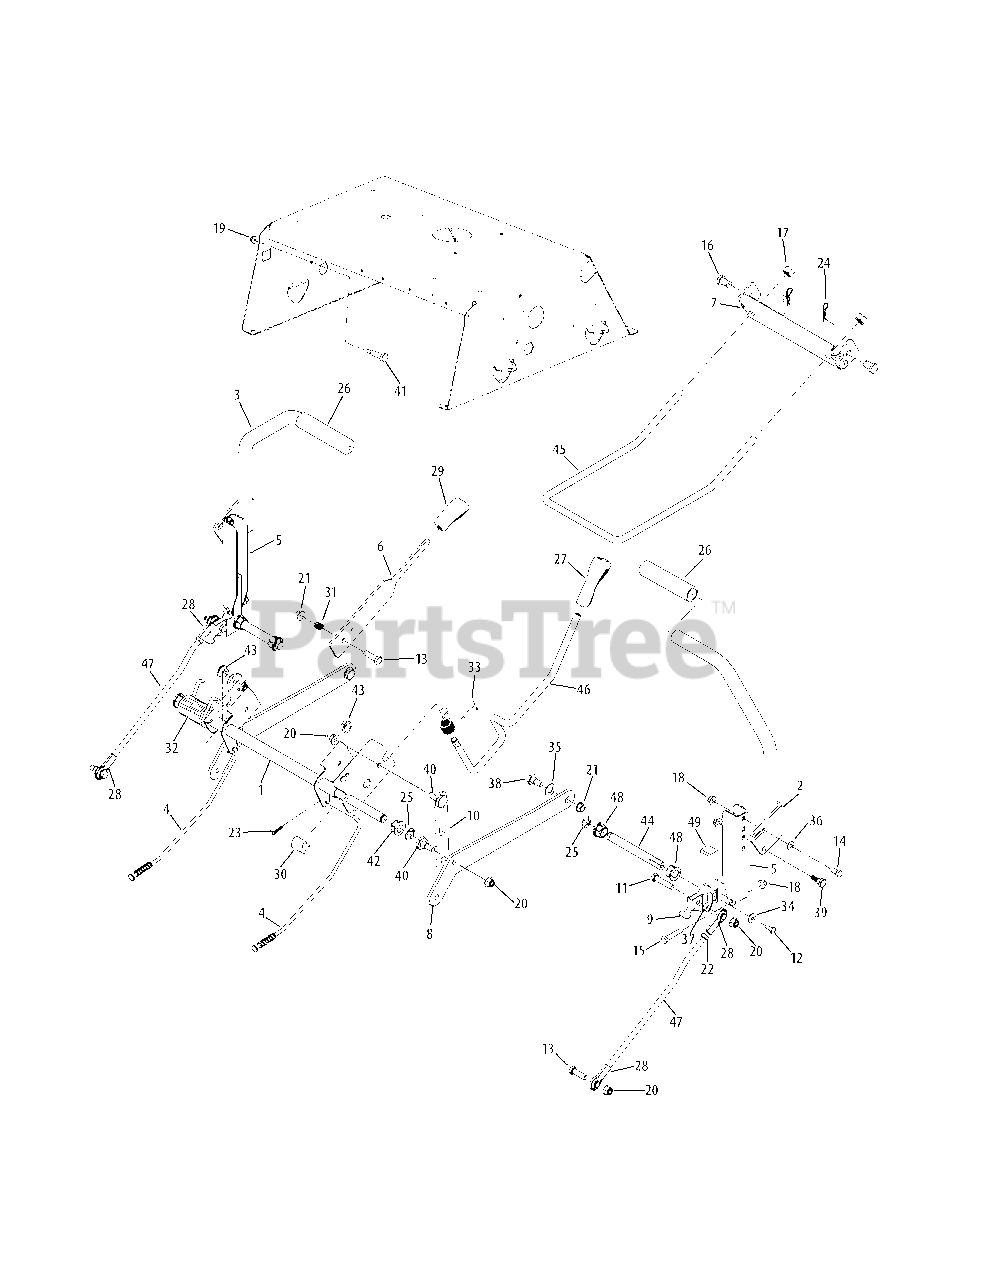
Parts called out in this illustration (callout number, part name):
1	Deck Lift Shift Assembly
2	RH Lapbar Lever Assembly - Black
2	RH Lapbar Lever Assembly - Gray
3	LH Labpar Lever Assembly - Black
3	LH Labpar Lever Assembly - Gray
4	Brake Rod Assembly
5	Lapbar Pivot Bracket
6	Brake/Shabs Assembly
7	Front Deck Hanger Bracket
8	Deck Lift Arm Plate
9	Switch Actuator Bracket
10	Lift Link Plate
11	Hex Screw, 3/8-16 x 1.75
12	Hex Screw, 1/4-20 x .625
13	Hex Screw, 3/8-16 x 1.25
14	Hex Screw, 5/16-18 x .75
15	Hex Screw, 5/16-18 x 1.75
16	Clevis Pin, .50 x .78
17	Flex Lock Nut, 1/2-13
18	Flange Lock Nut, 5/16-18
19	Flange Lock Nut, 1/4-20 (50" Deck)
20	Flange Lock Nut, 3/8-16
21	Hex Lock Nut, 3/8-16, Centerlock
22	Jam Nut, 3/8
23	Bow-Tie Cotter Pin
24	Cotter Pin, .080 x 1.5625
25	E-Ring
26	Lapbar Grip
27	Handle Grip, 1/2
28	Rod End
29	Selector Handle
30	Spacer, .621 x 1.00
31	Compression Spring, .50 x .50
32	Torsion Spring, 1.191 x 2.78
33	Spring, Torsion RZT
34	Bell Washer, .265 x .75 x .062
35	Flat Washer, .510 x 1.00 x .060
36	Flat Washer, .344 x .688 x .065
37	Spacer, .380 x .625 x .265
38	Shoulder Bolt, 3/8-16 x .496 x .336
39	Shoulder Screw, 5/16 x .437 x .268
40	Shoulder Screw, .500 x .434
41	Shldr. Screw, .374 x 1.16 (50" Deck)
42	Hex Flange Bearing
43	Flange Bearing, .626 x .938 x .344
44	Shaft Control
45	Front Hanger Deck Lift Rod
46	Deck Lift Handle Rod
47	Lapbar Control Rod
48	Hex Flange Bearing, .629
49	Control Hub
